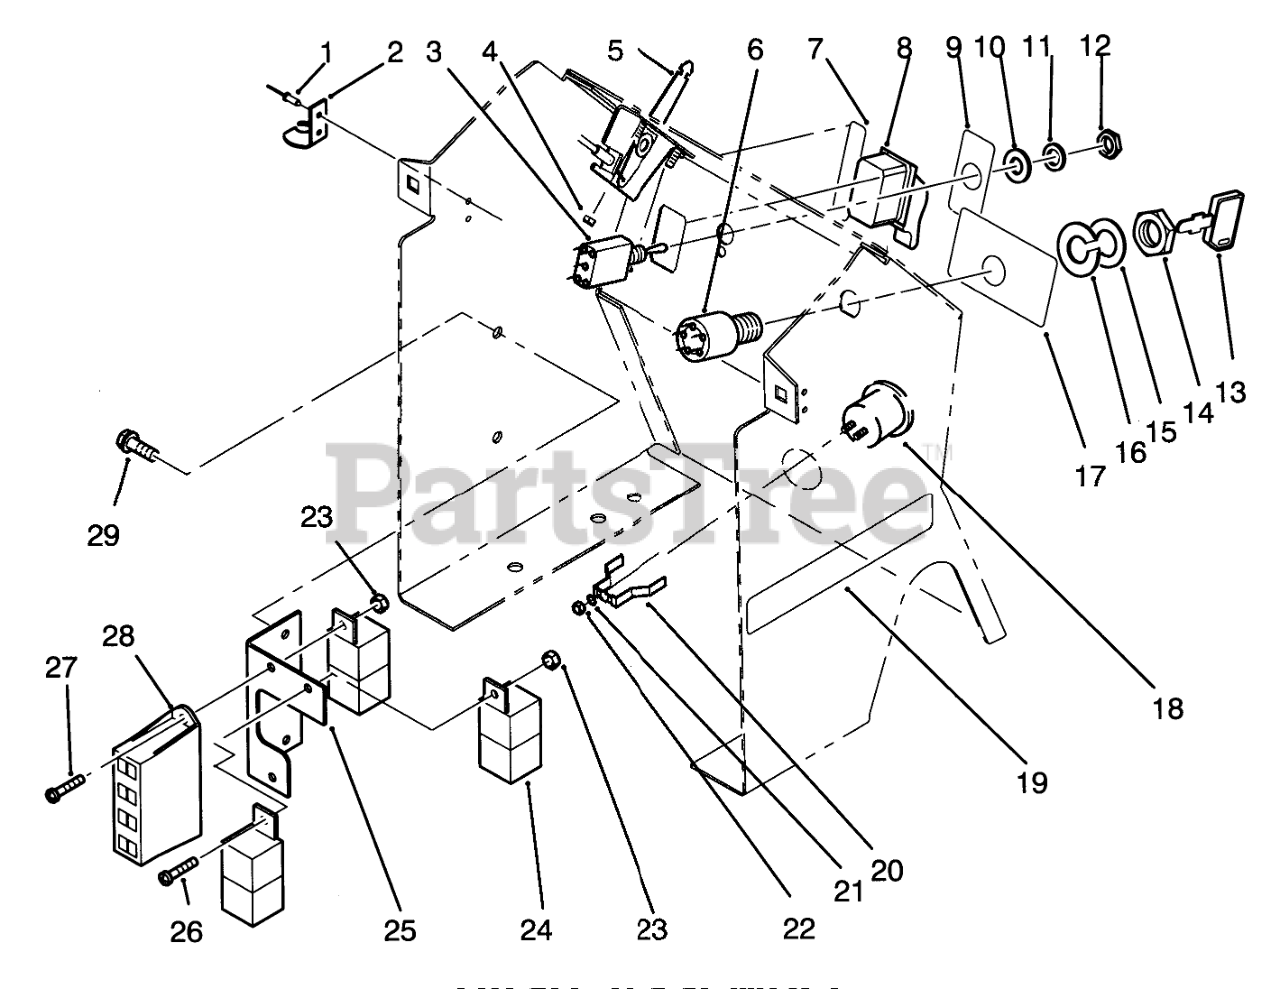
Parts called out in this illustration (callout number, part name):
1	POPRIVET 1/8X 1/8 BK
2	KEEPER-LATCH
3	SWITCH-LIGHTS
4	Nut
5	CONTROL-THROTTLE
6	Switch-Ignition, (Incl. Ref #6 & 13-17)
7	DECAL-PTO
8	PTO-SWITCH W/COVER
9	DECAL-LIGHTS
10	WIRE ASSY
11	Washer
13	KEY-IGNITION
15	Washer
16	LOCKWASHER
17	DECAL-IGNITION
18	HOUR-METER
19	DECAL-MODEL 5-SPEED
20	CLAMP-HOUR METER
21	WASHER-LOCK
22	Nut
23	Nut
24	RELAY
25	Bracket-Fuse Holder
26	SCREW-PPH
27	Screw
28	FUSE-HOLDER 4 WAY
29	TRS-1/4-20X1/2 BLACK
